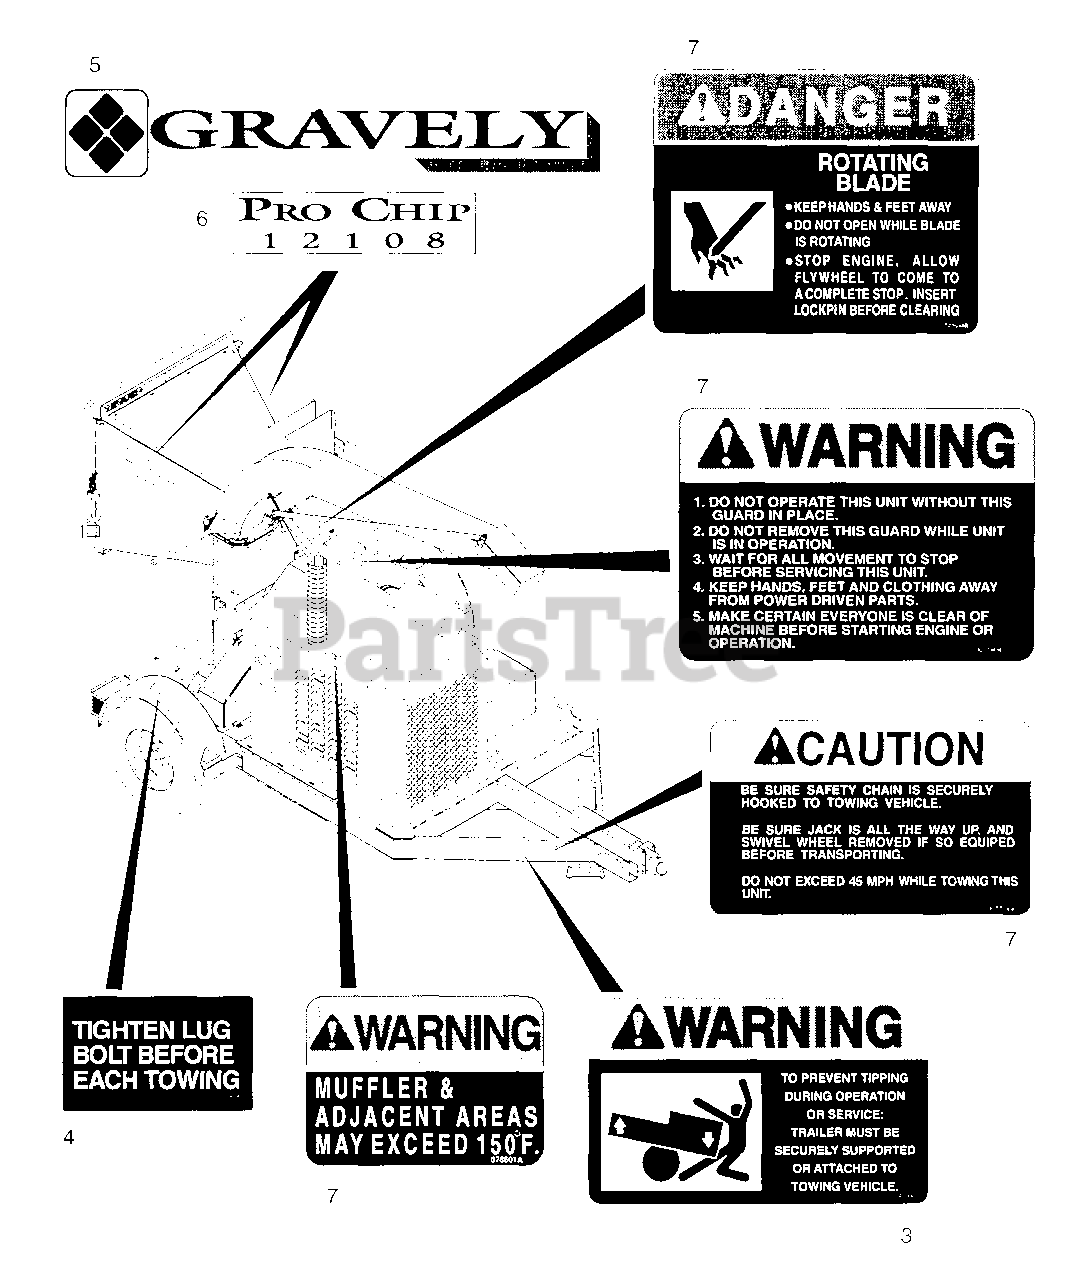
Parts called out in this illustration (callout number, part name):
3	Decal-WARNING-Tipping
4	Decal Set-Chipper Black/White
5	Decal-Gravely Name/Logo Set (2 Large and 1 Small)
6	Decal-Model Designation 12108- set of 2
6	Decal-Model Designation 1299 - set of 2
6	Decal-Model Designation 1281 - set of 2
6	Decal-Model Designation 1286 - set of 2
6	Decal-Model Designation 12110 - set of 2
6	Decal-Model Designation 12115 - set of 2
7	Decal Set-Large Chippers
